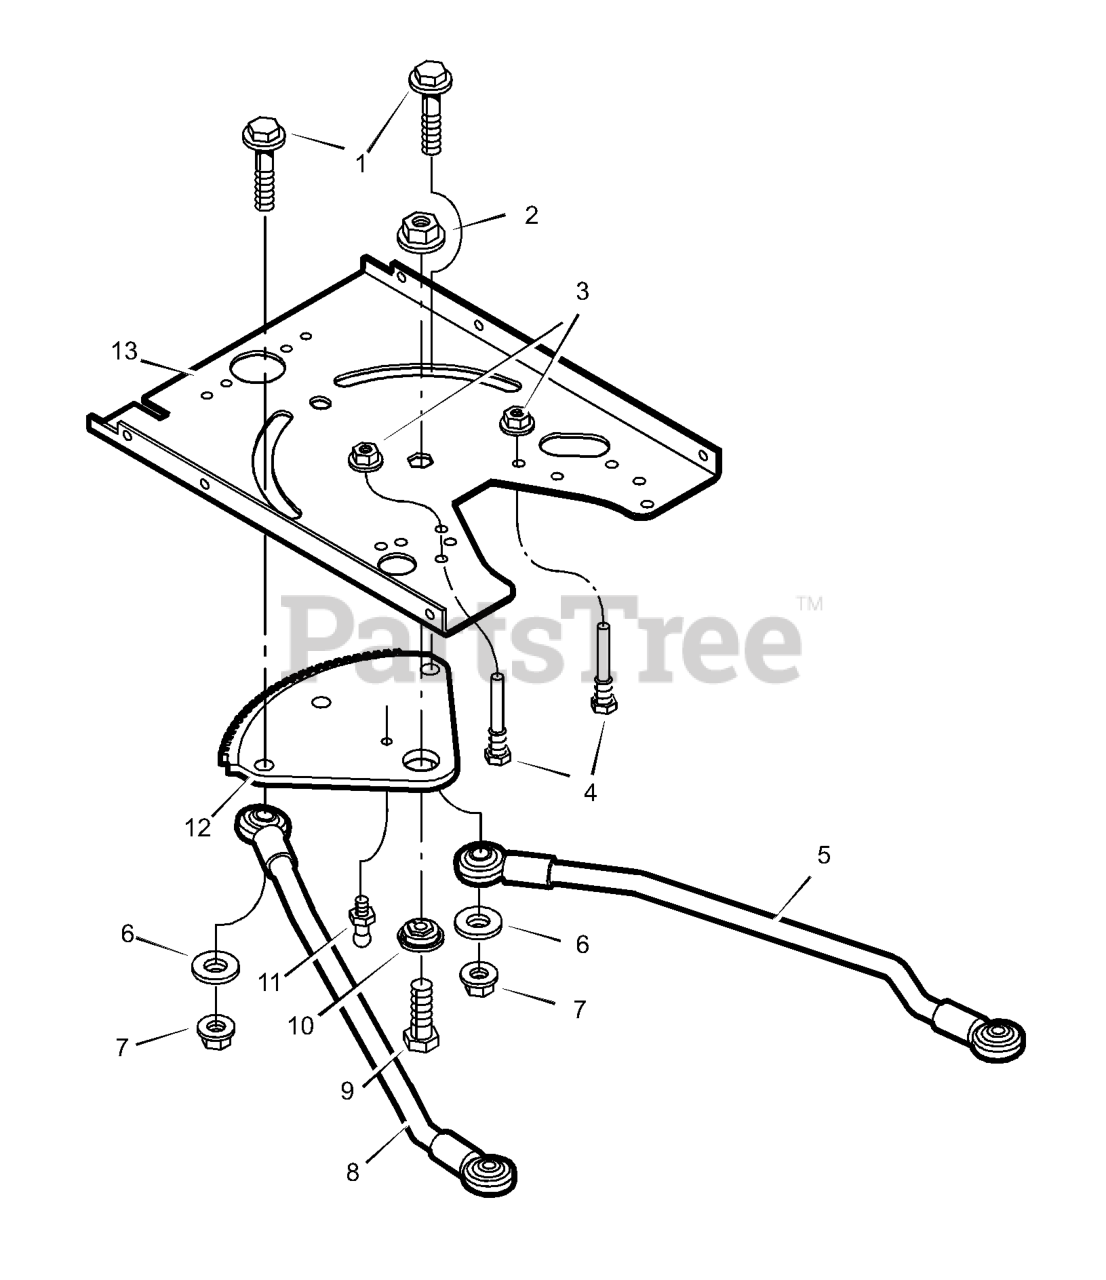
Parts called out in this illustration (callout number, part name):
1	Bolt, Shoulder
2	Nut, Lock
3	Nut, Flange
4	Guide, Screw
5	Link, Left Drag
7	Nut, Flange
8	Link, Right Drag
9	CAPSCREW, Hex Head, 5/16-18 x 1
10	Bearing, Sector Gear
11	Fitting, Lub
12	Gear, Sector
13	Plate, Steering
